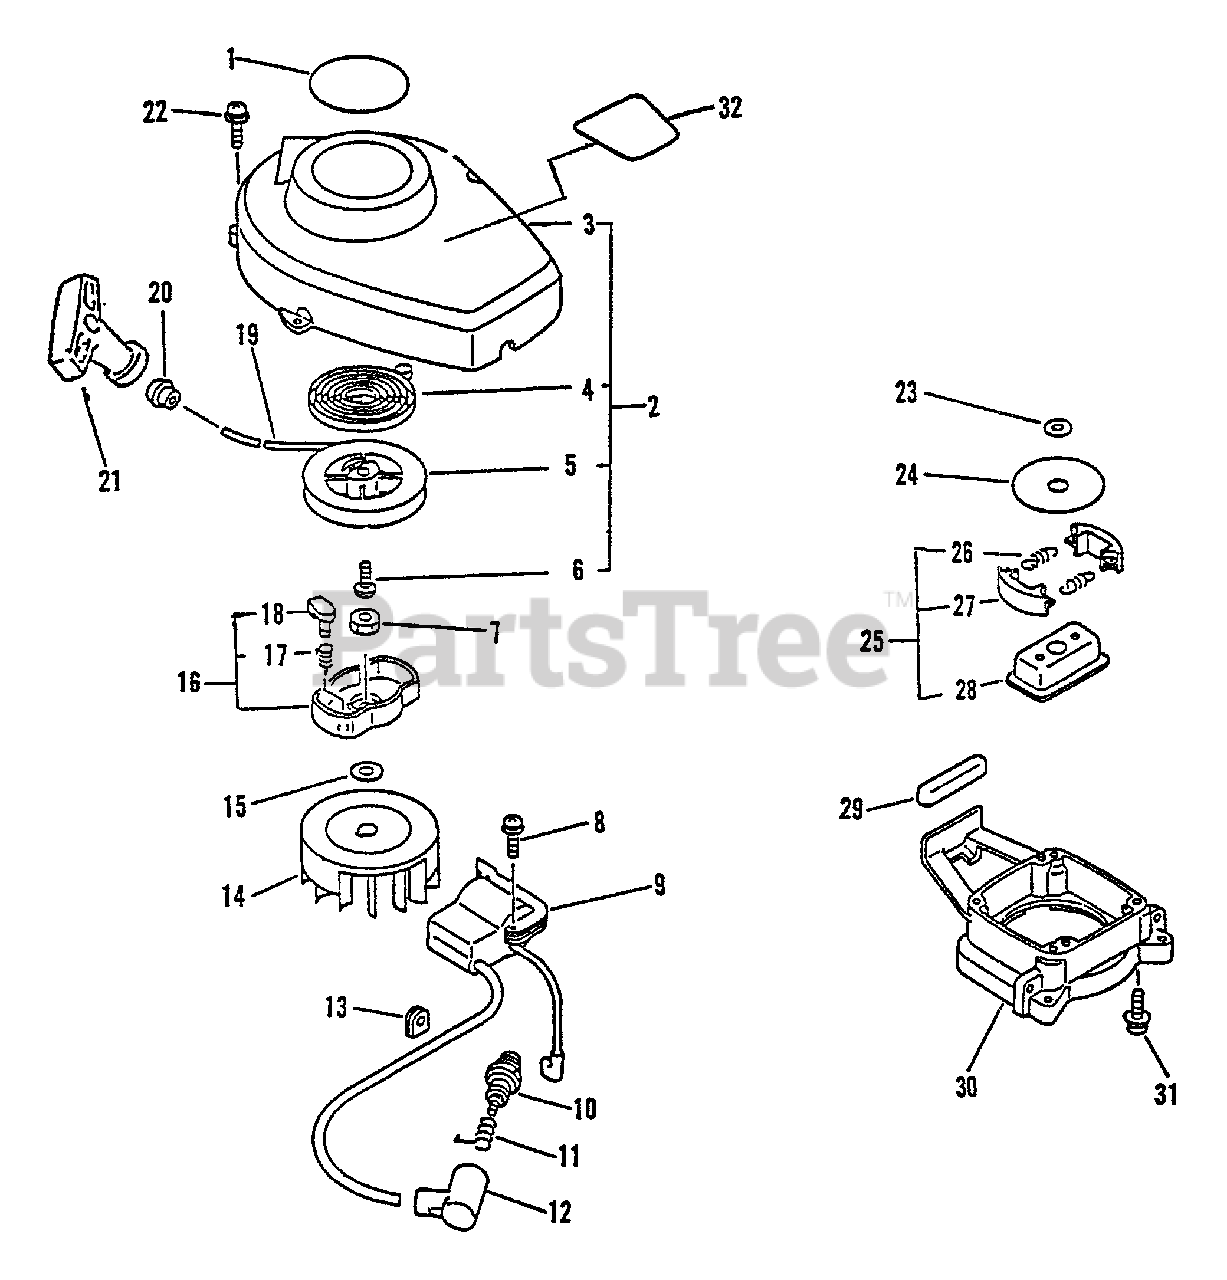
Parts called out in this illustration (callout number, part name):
2	STARTER ASSY
3	CASE, STARTER
4	SPRING, RECOIL
5	REEL, ROPE
6	SCREW
8	SCREW 4×22
9	COIL, IGNITION
10	SPARK PLUG - BPM7A
11	TERMINAL, SPARK PLUG
12	CAP, SPARK PLUG
14	FLYWHEEL
15	WASHER 8.5×16×1.2
16	STARTER PAWL ASSY
17	SPRING, RETURN
18	PAWL, STARTER - BLACK
20	GUIDE, ROPE
21	GRIP, STARTER
22	SCREW 4×16
23	WASHER, CLUTCH
24	PLATE, CLUTCH
25	CLUTCH ASSY
26	SPRING, CLUTCH
27	SHOE, CLUTCH
28	HUB, CLUTCH
29	CUSHION, FUEL TANK
30	CASE, CLUTCH
31	SCREW 4×16
32	LABEL MODEL -- LHS-3050
32	LABEL - MODEL LHS-4050
